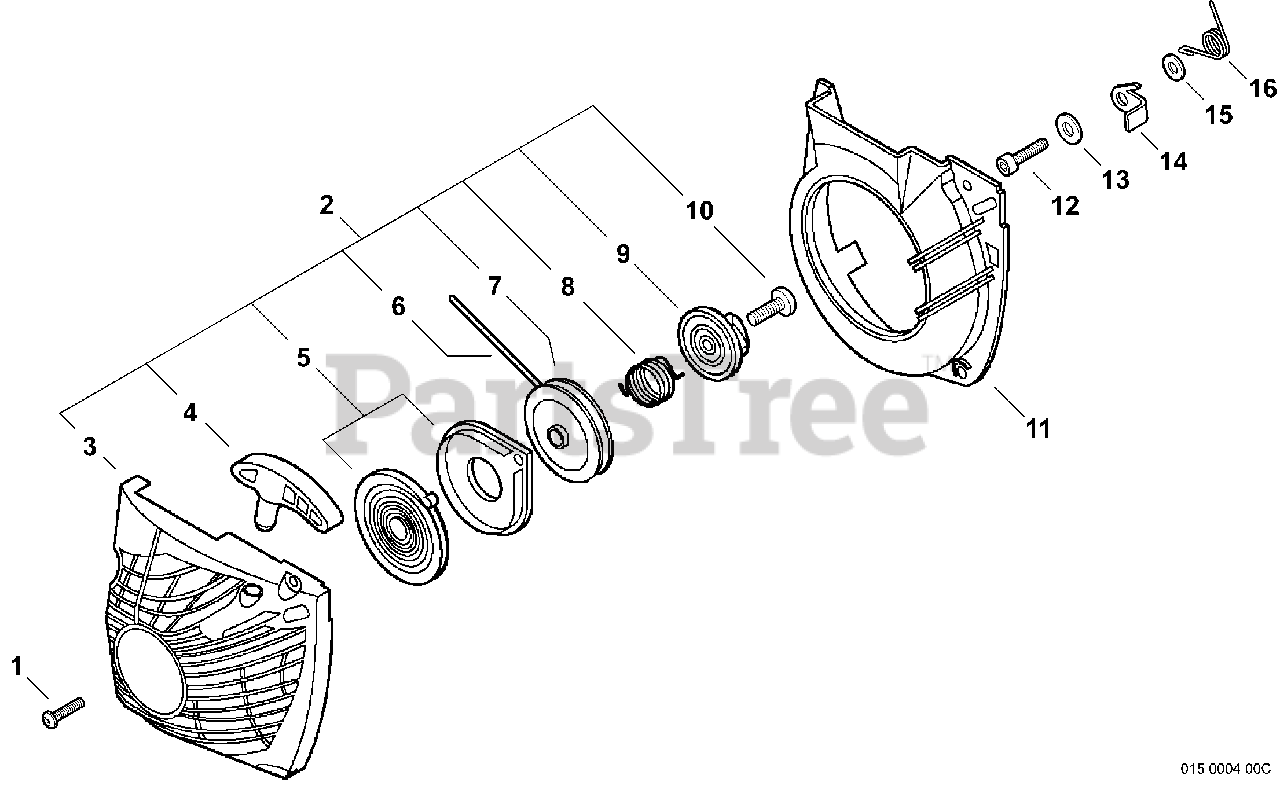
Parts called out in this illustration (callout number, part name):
1	SCREW TAPPING 5×20
2	STARTER ASSY, RECOIL - I-START
3	CASE, RECOIL STARTER
4	GRIP, STARTER
5	SPRING SET, RECOIL
6	ROPE, STARTER 3.5×900
7	REEL, ROPE
8	SPRING, TORSION
9	PAWL CATCHER
10	SCREW
11	COVER, FAN
12	BOLT 5×14
13	WASHER 5.5×12×0.8
15	SPACER 5.2×8×2.1
16	SPRING, TORSION
